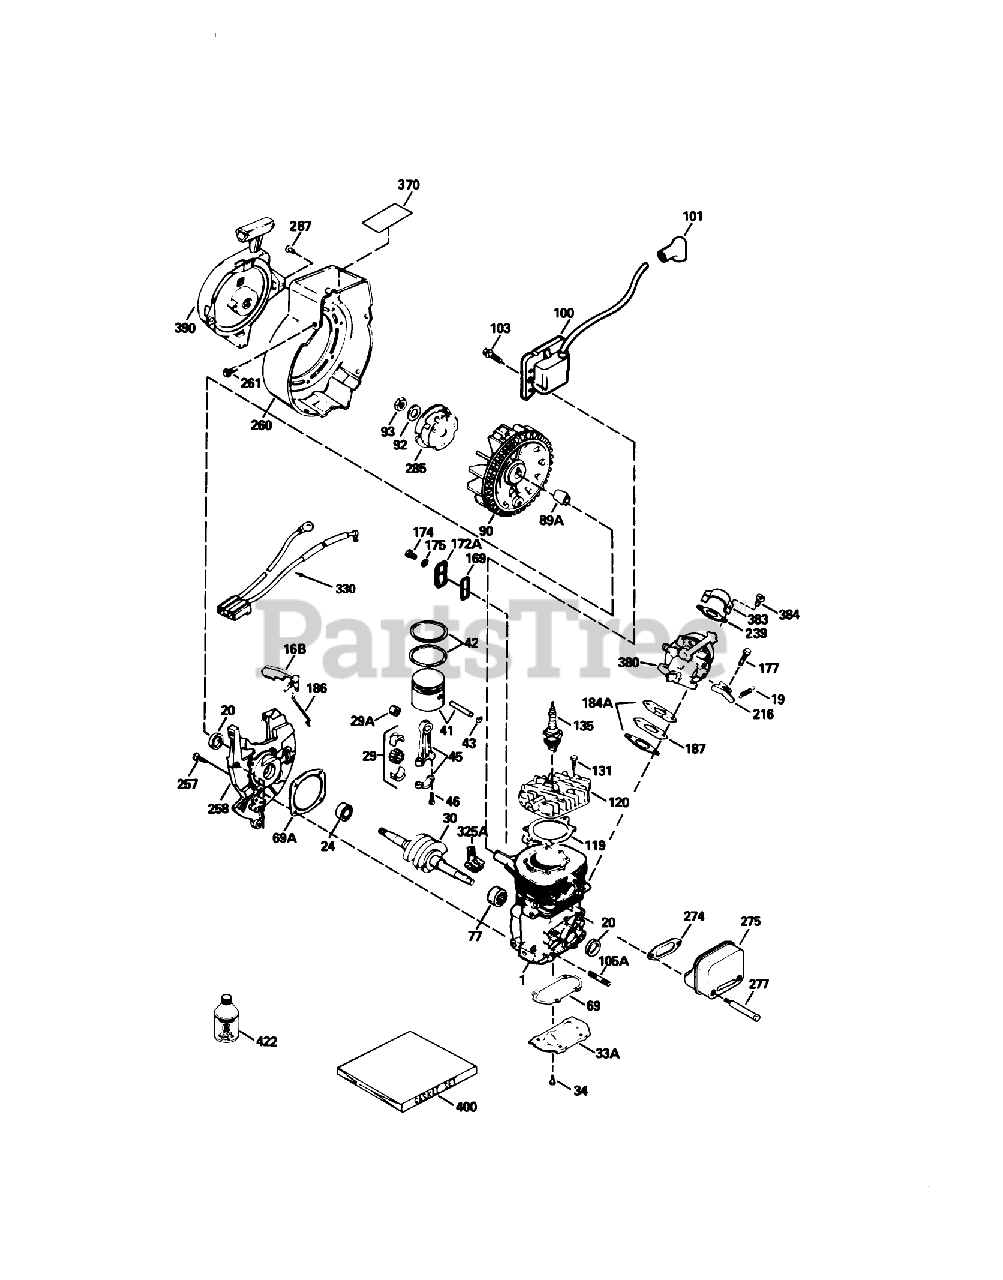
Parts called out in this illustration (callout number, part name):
1	Block Ass-y-Cylinder (Order short block if replacement is required)
16B	Vane-Air
19	Spring-Extention
20	Seal-Oil
24	Bearing-Ball
29	Needle Bearing and Liner Set (37 Needles)
29A	Bearing-Cartridge
30	Crankshaft
33A	Plate-Cover
34	Screw (T-25, 10-24 x 1/2)
41	Piston (Incl. Ref. #43)
42	Ring Set
43	Ring-Retaning
45	Rod Assy.-Connecting (Incl. Ref. #3, 3A 3B)
46	Bolt-Rod, Connecting
69	Gasket-Plate, Cover
69A	Gasket-Cover, Cylinder
77	Bearing-Cartridge
89A	Blade (20 inch)
90	Flywheel
92	Washer-Belleville
93	Nut-Flywheel
100	Solid State
101	Cover-Spark Plug
103	Screw
119	Gasket-Head, Cylinder
120	Head-Cylinder
131	Screw (T-30, 1/4-20 x 3/4)
135	Spark Plug-Resistor (R C J 8Y)
169	Cover-Compression, Release
172A	Comp. Release Cover
174	Screw (T-25, 10-24 x 1/2)
175	Washer
177	Screw (5/32 Allen, 1/4-20 x 1)
184A	Gasket-Carburetor
186	Link-Governor
187	Spacer
216	Lever-Adjusting, Rpm
239	2060A77 WIZARD ROTA
257	Screw (T-30, 1/4-20 x 5/8)
258	Base Assy.-Blower Housing (Incl. Ref. #10)
260	Housing-Blower
261	Screw (1/4-20 x 1/2)
274	Gasket-Exhaust
275	Muffler (Incl. Ref. #274 277)
277	Screw (1/4-20 x 2-3/4)
285	Cup-Starter
287	Rivet-Pop
325A	Clip-Wire
330	Harness-Wire
370	Decal-Warning
380	Carburetor (Incl. Ref. #184A)
383	Baffle-Carburetor
384	Screw
390	Starter-Rewind
400	Gasket Set
422	2-Cycle Oil (8oz)
